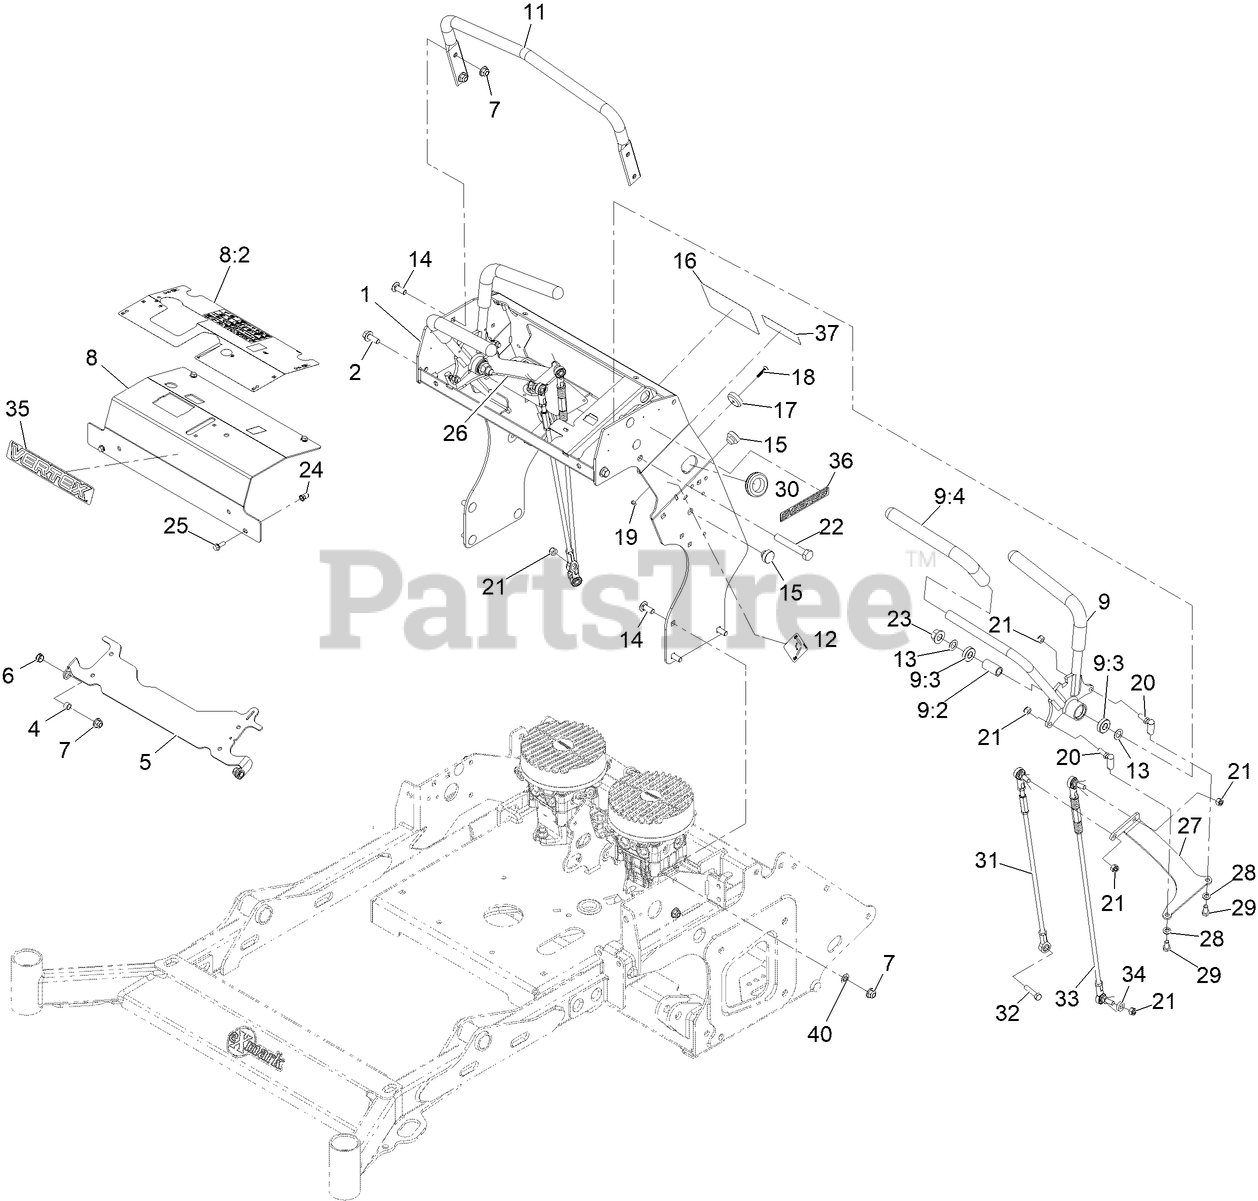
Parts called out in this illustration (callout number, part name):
1	ASM-Tower [red]
2	SCREW-HHF 3/8-16 X 1
4	SPACER-BRAKE PIVOT
5	Spacer-Brake Pivot
6	BUSHING,SNAP
7	NUT-HF, NI
8	ASM-CTRL PNL W/DCL EFI
8:2	Decal-Control Panel EFI
9	ASM-CTRL LEVER
9:3	BEARING-WHEEL
9:4	GRIP-HANDLE, CONTROL
11	BAR-REFERENCE
12	DECAL-PARK BRAKE, CE
14	SCREW-CARR
15	BUMPER-RUBBER
16	DECAL-SERVICE AID
17	MAGNET-RARE EARTH THIGH PAD
18	SCREW FLAT HD #10-24X1.00
19	NUT-LOCK
20	BALLJOINT-RH (W/GROMMET)
21	NUT-LOCK
22	SCREW-HH
23	Nut-Lock 1/2-13
24	Nut-Clinch, Hex
25	SCREW-HHF
26	BRACKET-LINK CTRL LH
27	BRACKET-LINK CTRL RH
28	WASHER-LOCK
29	SCREW-HH
30	GROMMET
31	ASM-MOTION CONTROL SHORT
32	SCREW-HH
33	ASM-MOTION CONTROL LONG
35	DECAL-VERTEX LOGO
36	Decal-S-Series
37	DECAL-FUSE
40	NUT-PUSH
